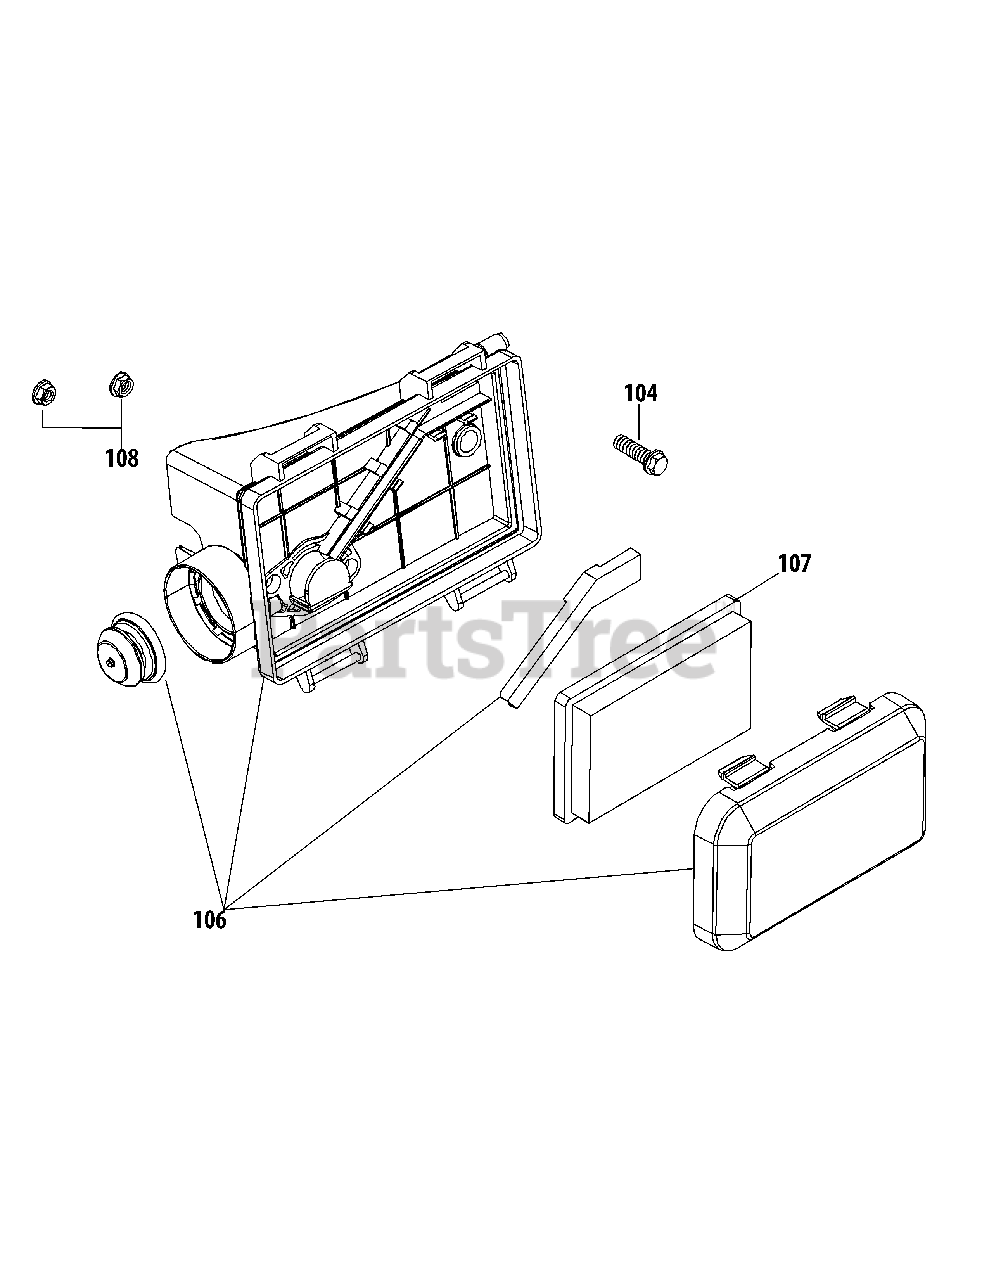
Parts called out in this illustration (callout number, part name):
104	BOLT-M6-1 x 30 GR8.8
106	AIR FILTER ASSEMBLY
106	AIR FILTER COVER
106	BREATHER COVER
106	AIR FILTER BASE
106	PRIMER BULB (NON-VENTED)
107	AIR FILTER
